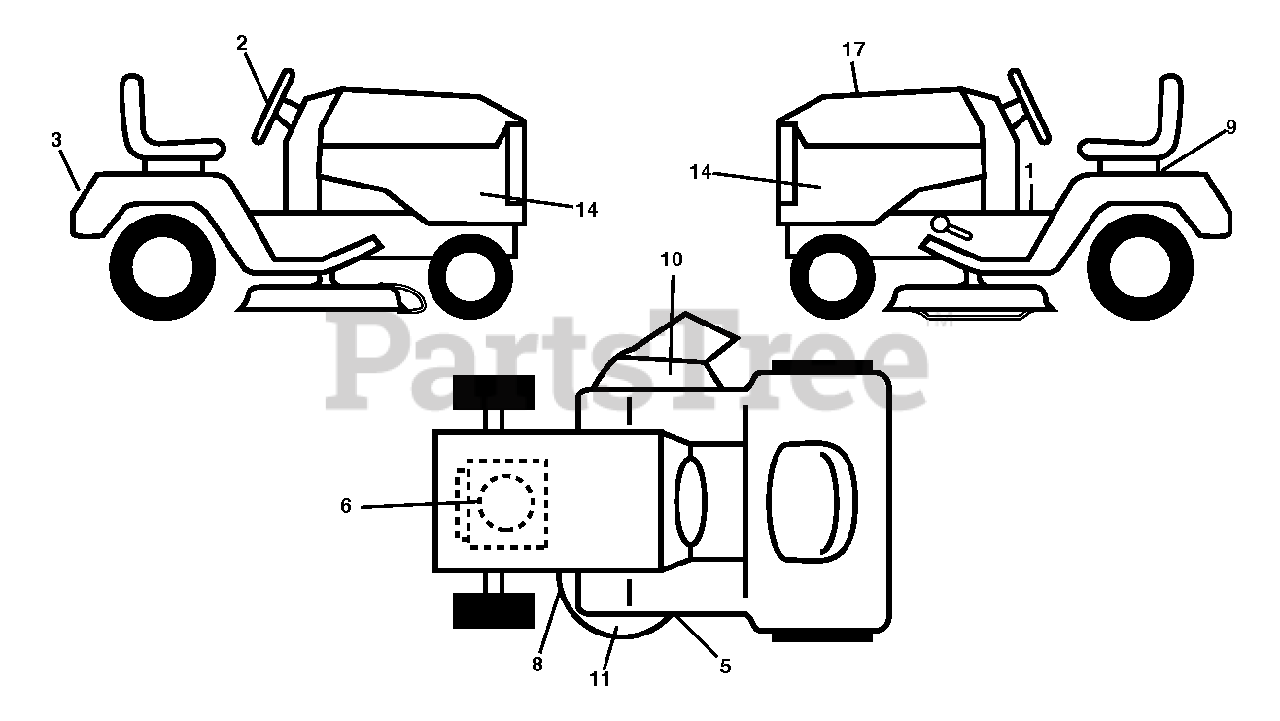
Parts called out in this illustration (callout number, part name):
1	DECAL.FENDER.WARNING.ENGLISH
2	DECAL.STRWHL.BLK.2014.PPRO
3	DECAL.REARFNDR.POULAN PRO.2015
5	DECAL.MOWER.CAUTION.TENSION.AR
6	DECAL.ENG.BS.24INTK.DOM.381710
8	DECAL.MOWER.SCH.48/54.PREM
9	DECAL BTRY SYMBOLS
10	DECAL, DECK DEFLECTOR, WARNING
11	DECAL.PPRO.10YRDECKWAR.POP
14	DECAL TRACTOR SIDE PANEL DECAL
17	DECAL.RPL.BSM44.TLW.54.GENTR
